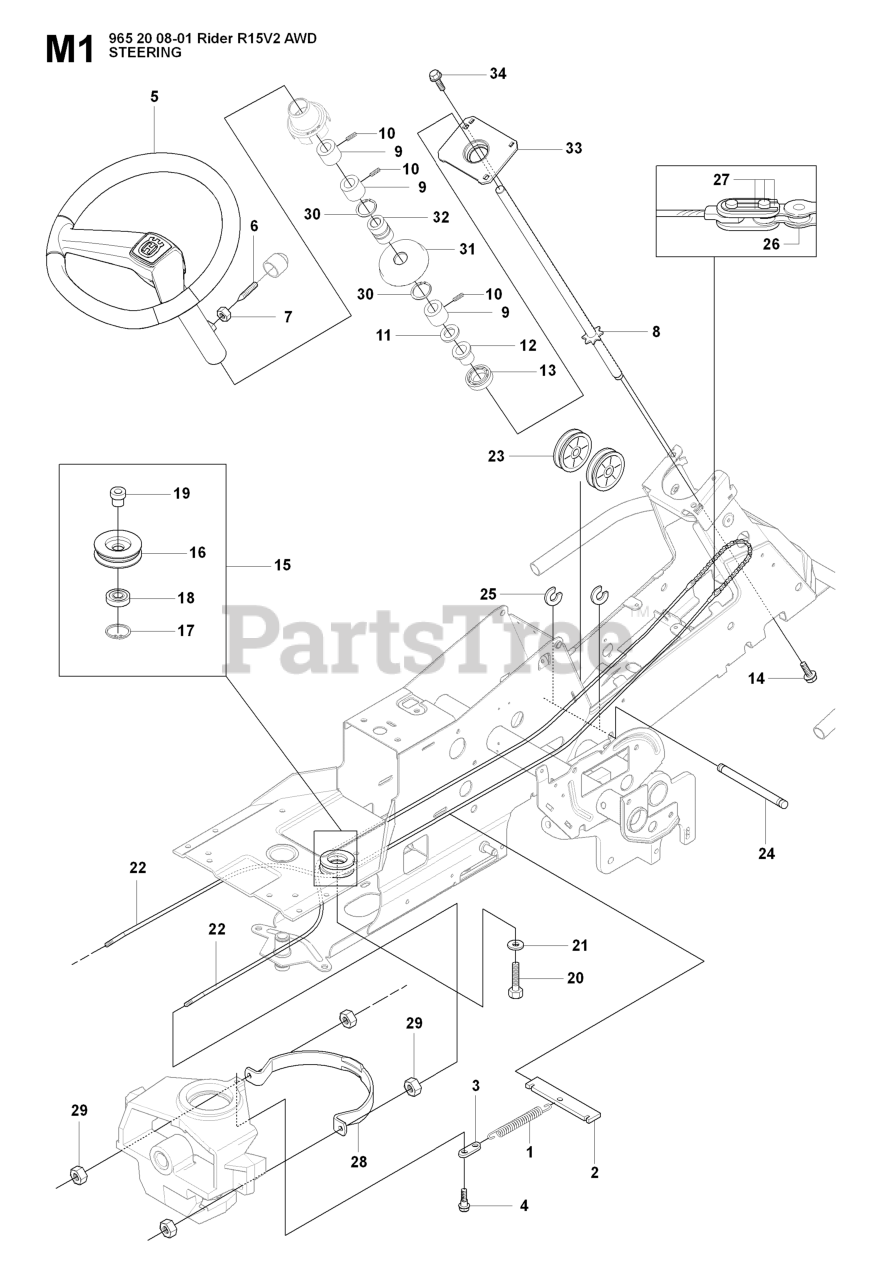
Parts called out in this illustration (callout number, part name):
2	SPRING BRACKET
7	NUT
9	SPACER
13	BALL BEARING 6004-2RS1
17	CIRCLIP SGH 47
18	BALL-BEARING 6204-2RS
22	RP STEERING CABLE COMPLETE
25	RETAINING RING
26	STEERING CHAIN
28	WIRE GUIDE
29	NUT
30	RETAINING RING SGA 25
